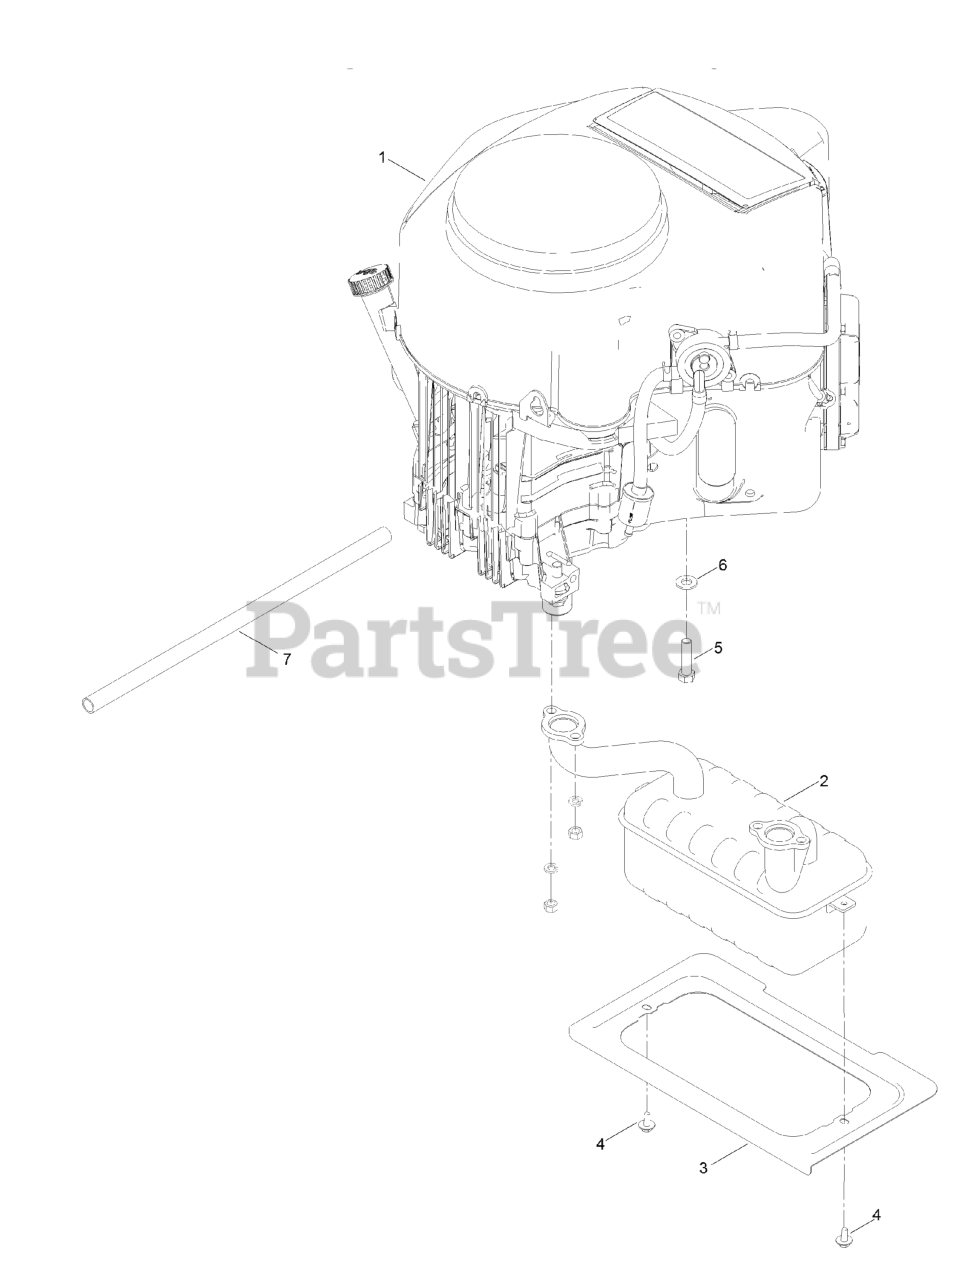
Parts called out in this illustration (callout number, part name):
2	Muffler
3	SHIELD-HEAT
4	SCREW-HHFTF
5	BOLT-HH
6	WASHER-FLAT
7	TUBE-DRAIN, OIL
